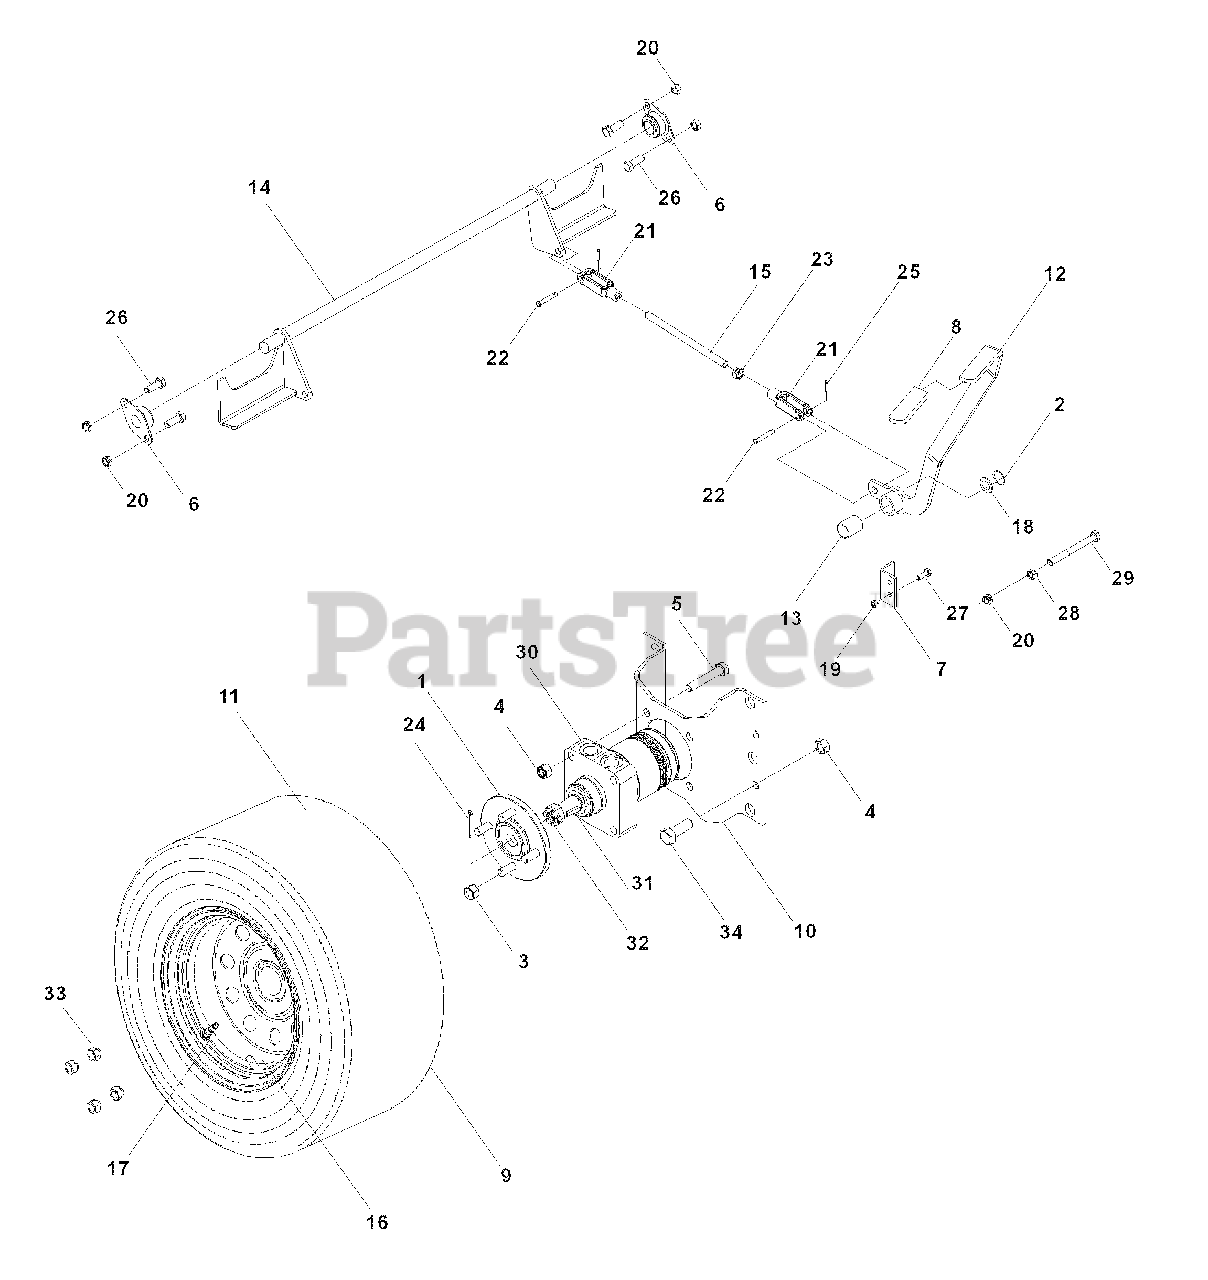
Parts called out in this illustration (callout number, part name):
2	7/8 RETAINING RING
4	NYLOC 1/2C NUT
5	HCS 1/2C x 2 3/4
6	FLANGE BEARING
9	TIRE
10	MOTOR STANDOFF
11	TIRE
12	BRAKE LEVER WLDMT
14	BRAKE CROSS SHAFT
17	VALVE STEM
18	MACHINE BUSHING
19	1/4C NYLOC NUT
20	NYLOC NUT 3/8C
22	3/8X 1 1/8 CLEVIS PIN
24	COTTER PIN
25	COTTER PIN
26	HCS 3/8C x 1
27	HCS 1/4C x 3/4
28	WHIZ NUT 3/8C
29	HCS 3/8C x 2 1/2
30	WHEEL MOTOR
31	KEY WOOODRUFF
32	CASTLE NUT
34	HCS 1/2C x 1 1/4
